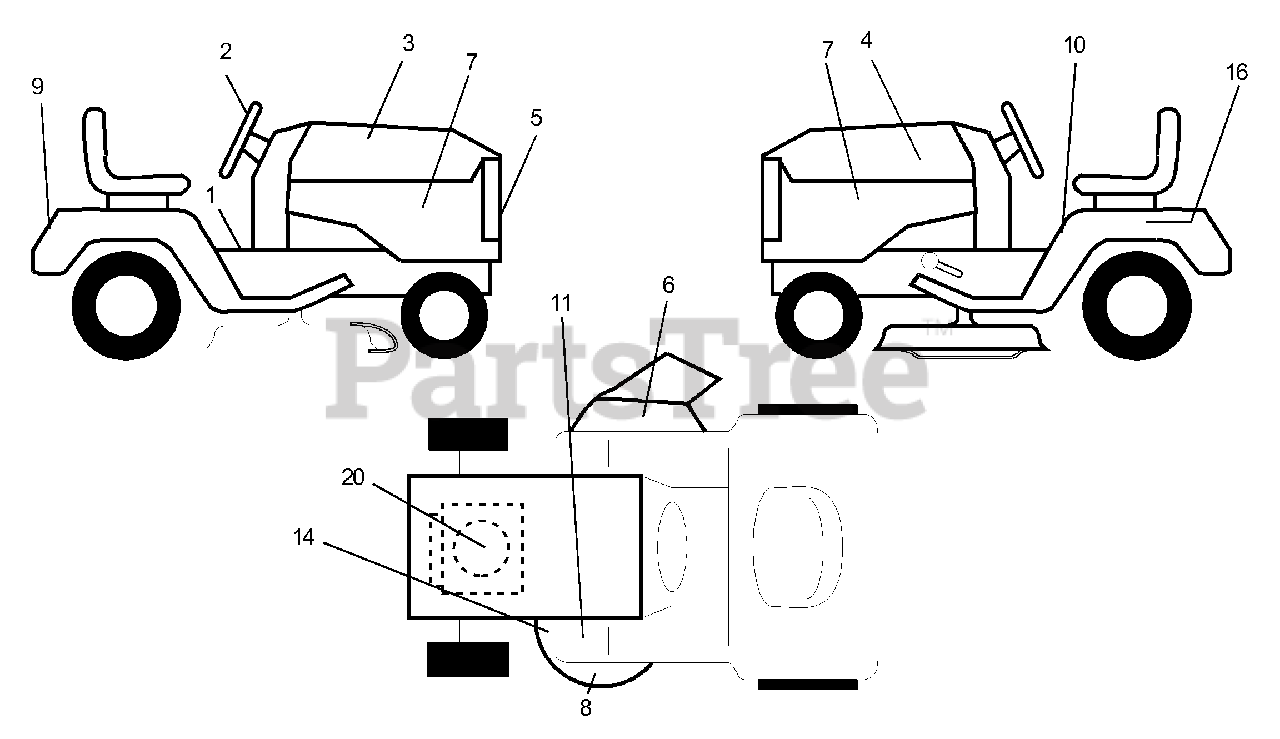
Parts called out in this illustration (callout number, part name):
1	Decal Inst Operate English/French
2	Decal Ins Strg Wh
3	Decal Hood Rh
4	Decal Hood Lh
5	Decal Grille Logo
6	Decal, Warning
7	Decal Panel Side
8	Decal Deck Grasseater
9	Decal Fender Logo
10	Decal Danger English/French
11	Decal Clutch/brake English/French
14	Decal V-belt Schematic 42"
16	Decal Battery Danger/Poison
20	Decal HP Engine
